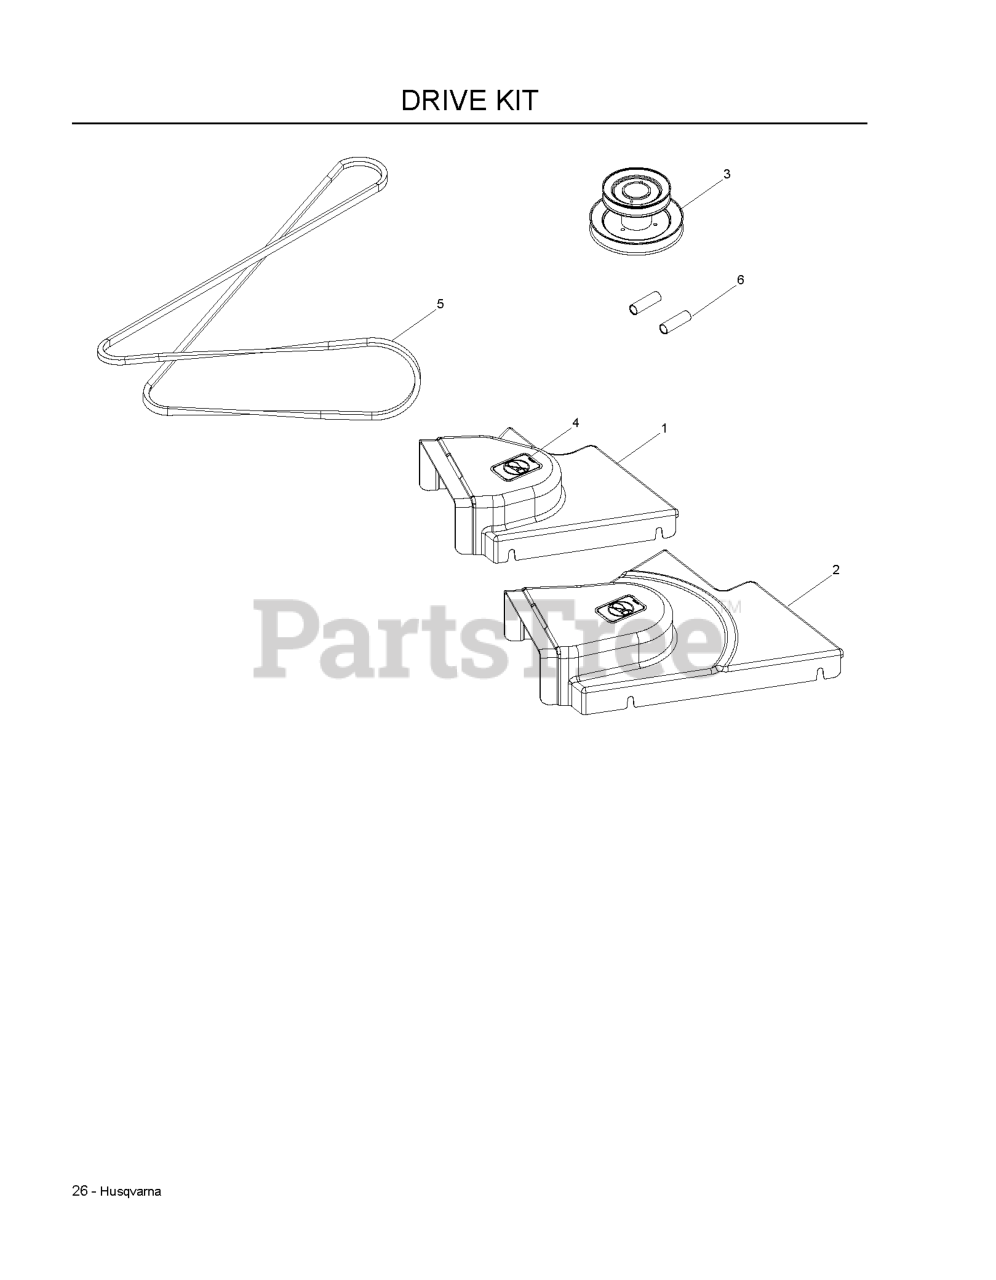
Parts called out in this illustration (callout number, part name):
3	PULLEY, 52" STACK
3	PULLEY, 61" STACK
4	DECAL, NO STEP
6	TUBE, DECK STOP
